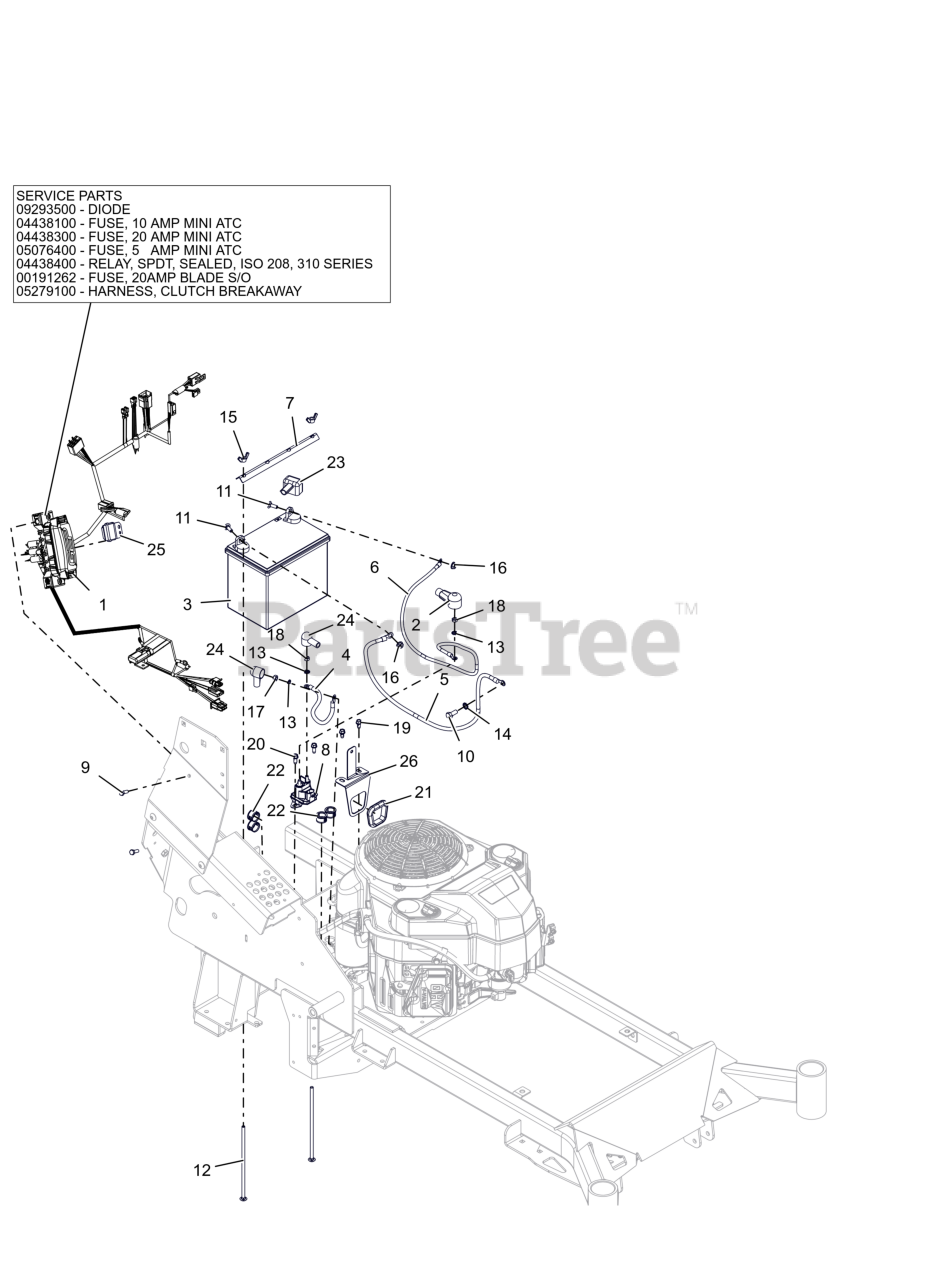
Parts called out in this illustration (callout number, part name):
1	HARNESS, WIRE PROSTANCE 2019
1	DIODE, CONNECTOR SHELL
1	FUSE,10 AMP MINI-ATC
1	FUSE,20 AMP MINI ATC
1	FUSE, 5 AMP MINI-ATC
1	RELAY,MICRO5 TERML W/RESISTOR
1	FUSE, 20 AMP BLADE S/O
1	HARNESS, CLUTCH BREAKAWAY
2	BOOT, BATTERY TERMINAL-RED
3	BATTERY, 300 CCA 10U1L
4	CABLE-POSITIVE BATTERY 9.00"
5	CABLE-NEGATIVE BATTERY 24.00"
6	CABLE-POSITIVE BATTERY 26.00"
7	HOLD DOWN
8	SOLENOID, STARTER (SEALED)
9	BLT,HEX M6-1X20 G8.8 ZC120
10	BLT, HEX M8-1.25X20 G8.8 ZCC
11	BLT, RHSN .25-20X.750 G5 ZCC
12	BLT, RHSN .25-20X7.50 G5 ZCC
13	WSHR,LK-EXT.262X.502X.026 ZCC
14	WSHR,LK-EXT .326X.599X.031 ZCC
15	NUT- LK-WING .25-20 ZCC
16	NUT-SPNLK-FLG .25-20 ZC120
17	NUT-STD .250-20 G2 ZCC
18	NUT-STD M6-1.0 ZCC
19	SCR-TAP .25-20X.50 HWH ZCC
20	SCR,TAP .25-20X.625 HWH ZCC
21	GROMMET 1.70ID X 2.0OD
22	BUSH, PANEL SNAP .687X.875X.56
23	INSULATOR
24	BOOT, EYELET TERMINAL
25	MODULE,INTERLOCK,DELAY, 1801
26	GUARD, CLUTCH HARNESS ROUTING
